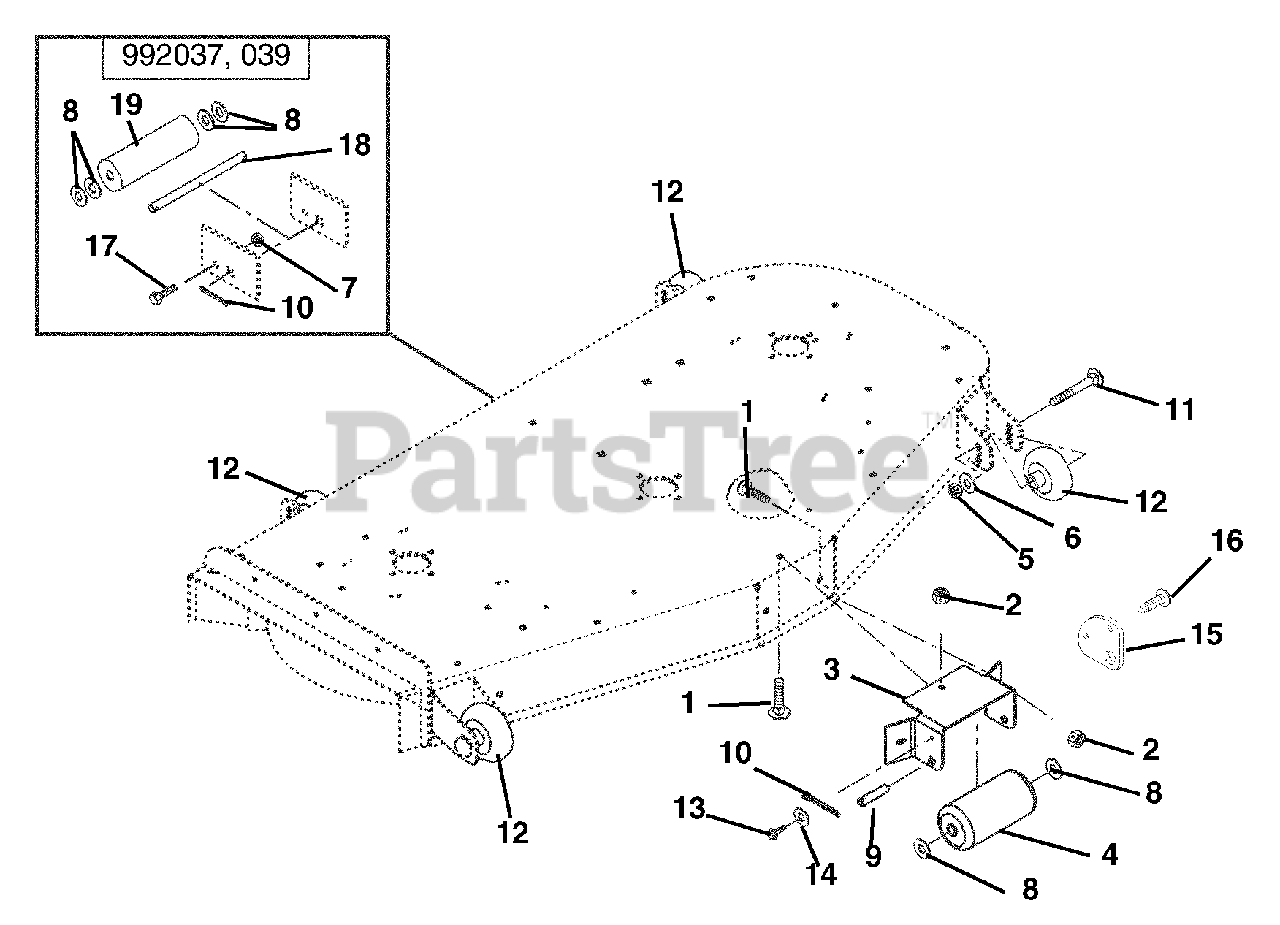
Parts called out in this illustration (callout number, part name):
1	Bolt-Round Head Square Neck .38-16 x 1.00 Grade 5
2	Nut, Locking Top Flange .38-16
3	Bracket, Anti-Scalp Roller
5	Nut-Locking-Nylon .50-13
6	Washer-Flat-Steel .531 x 1.06 x .095
7	Nut, Locking Center .25-20
8	Washer-Flat-Steel .656 x 1.31 x .095 (036, 038, 309)
8	Washer-Flat-Steel .656 x 1.31 x .095 (037, 039)
9	Pin, 9.41 x .625
10	Pin-Cotter .25 x 2.00 (036, 038, 309)
10	Pin-Cotter .25 x 2.00 (037, 039)
11	Bolt-Round Head Square Neck .50-13 x 5.00 Grade 2
12	Wheel, 3 x 5
13	Screw-Self Tapping .25-20 x .50 x Hex Washer Head
14	Washer-Flat-Steel .281 x .62 x .065
15	Anti-Scalp Washer
16	Screw-Tapping .250-20X.62 Hex Washer Head
17	Bolt-Hex .25-20 x .75 Grade 5
18	Shaft, Center Roller (037, 039)
19	Roller, Gage (037, 039)
